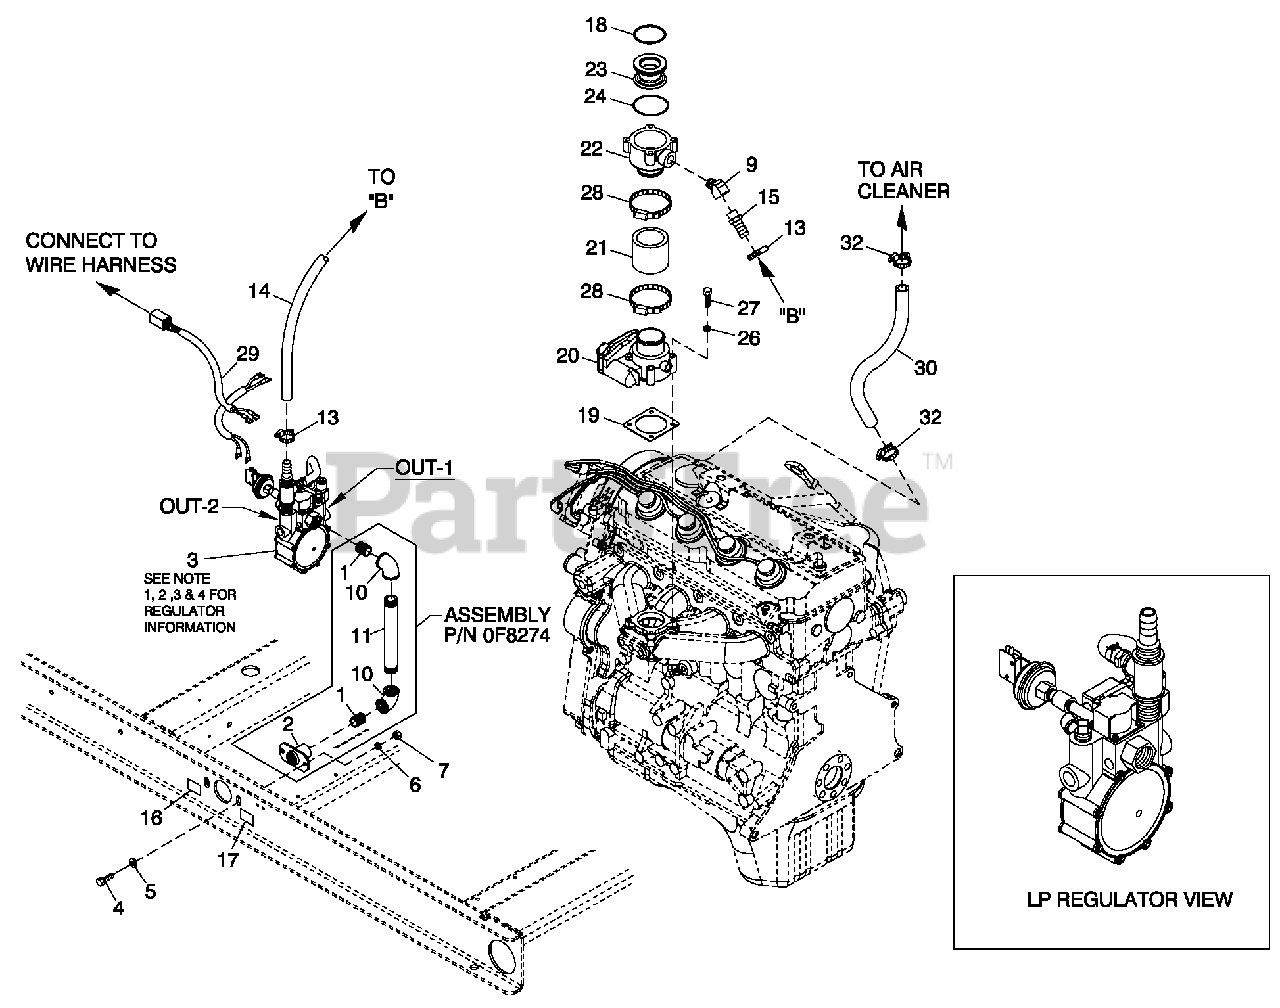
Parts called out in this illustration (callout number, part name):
1	NIPPLE CLOSE 3/4 X 1.375
2	FLANGE FUEL INLET
3	REGULATOR ASSY 2.4L (25KW)
4	SCREW HHC M8-1.25 X 20 G8.8
5	WASHER FLAT 5/16-M8 ZINC
6	WASHER LOCK M8-5/16
7	NUT HEX M8-1.25 G8 CLEAR ZINC
9	STREET EL 45D 1/2 NPT BRASS
10	ELBOW 90D 3/4 NPT
11	NIPPLE PIPE 3/4 NPT X 7
13	CLAMP HOSE #10 .56 - 1.06
14	HOSE 3/4 ID SAE-30R2 (18" LG)
15	BARBED STR 1/2 NPT X 3/4
16	DECAL INLET PRESSURE
17	DECAL FUEL INLET NG (NATURAL GAS APPLICATION)
18	O-RING 45.63 ID X 2.62 WIDTH
19	GASKET BOSCH 32
20	ACTUATOR BOSCH 40 GOVERNOR (45KW)
21	HOSE COOL 2 IN ID 20R4 (45KW)
22	VENTURI HOLDER W/40MM ACTUATOR (45KW)
23	VENTURI THROTTLE 26MM (35 & 45KW)
24	O-RING 47.625 ID X 2.38 WIDTH
26	WASHER LOCK M6-1/4
27	SCREW SHC M6-1.0 X 45 G12.9
28	CLAMP HOSE #28 1.32-2.25
29	HARNESS CPL FUEL JUMPER
30	HOSE 3/8 ID SINGLE BRAID (18" LG)
32	CLAMP HOSE #10 .56-1.06
